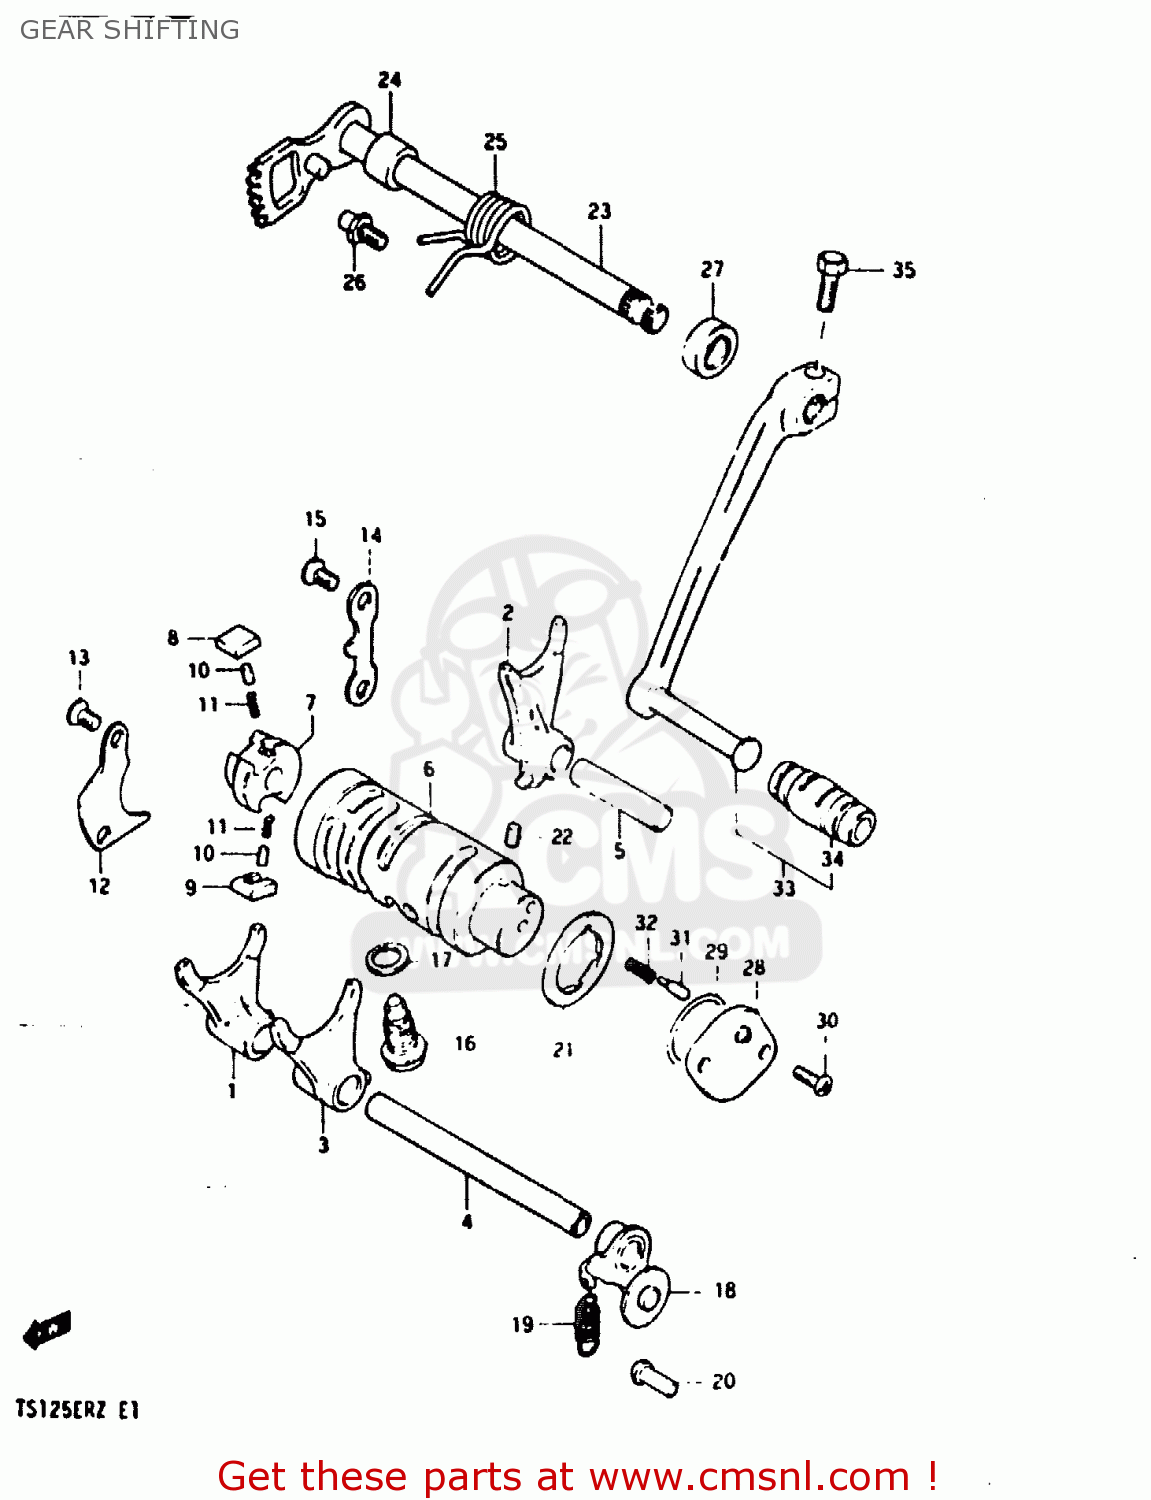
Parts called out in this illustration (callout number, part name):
1	FORK,GEAR SHIFT NO.1
2	FORK,GEAR SHIFT NO.2
3	FORK, NO.3
4	SHAFT,GEAR SHIFT FORK
5	SHAFT,GEAR SHIFT FORK
6	CAM,GEAR SHIFT
7	RETAINER,GEAR SHIFT CAM
8	PAWL,GEAR SHIFT NO.1
9	PAWL,GEAR SHIFT NO.2
10	PIN(5X8)
11	SPRING
12	LIFTER,GEAR SHIFT PAWL
13	SCREW
14	GUIDE,GEAR SHIFT CAM
15	SCREW
16	HOUSING, STOPPER CAM
17	GASKET(14X19.2X2) (NAS)
18	STOPPER,GEAR SHIFT CAM
19	SPRING
20	RIVET
21	PLATE,GEAR SHIFT CAM STOPPER
22	PIN 4X6
23	SHAFT,GEAR SHIFT
24	SPACER(12X20X15.3)
25	SPRING
26	STOPPER,GEAR SHIFT CAM
27	OIL SEAL
28	BODY,GEAR SHIFT SWITCH
29	O-RING (D:2.4 ID:26.2)
30	SCREW
31	PIN(5X15.5)
32	SPRING
33	LEVER ASSY,GEAR SHIFT
34	RUBBER,GEAR SHIFT PEDAL
35	BOLT
